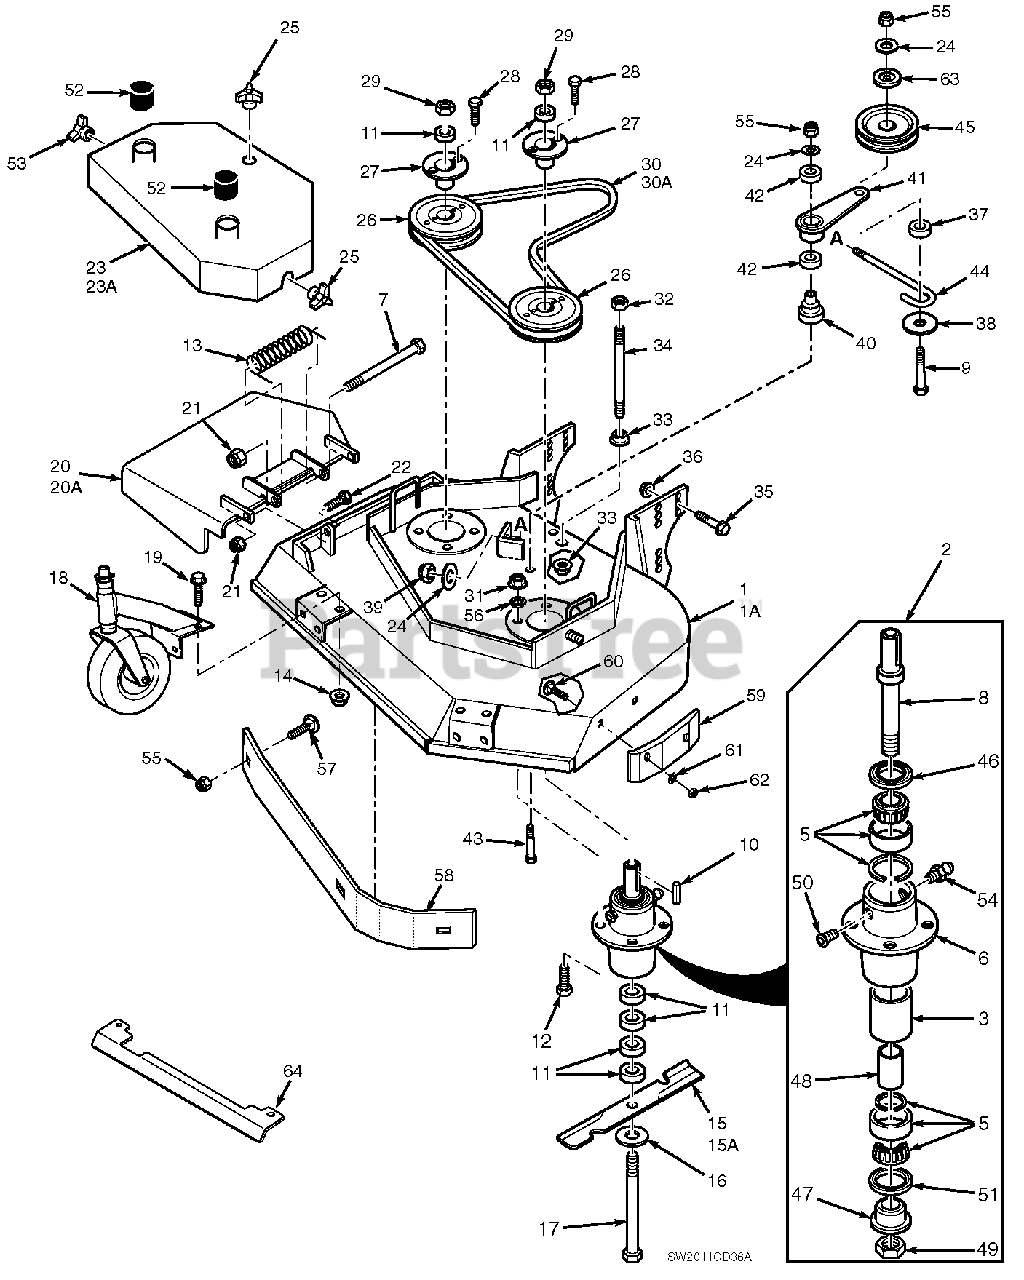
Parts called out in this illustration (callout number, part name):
1	Cutter Deck w/Decals
1A	Cutter Deck w/Decals
1A	Cutter Deck w/Decals - LE
2	Cutter Spindle Assembly
3	Spacer, Outside
5	Bearing, Tapered
6	Spindle Housing
7	Bolt, 5/16-18 x 4-3/4"
8	Spindle Shaft
9	Bolt, 3/8-16 x 3-3/4" Hex Head
10	Key, 1/4 x 1/4 x 2"
11	Spacer, Cutter Blade - Small
12	Bolt, 5/16-18 x 1-1/2" Hex Head Grade 8
13	Spring, Chute Return
14	Nut 5/16-18 Serrated Flange
15	Cutter Blade, 16-1/2"
15	Cutter Blade, 18"
15A	Cutter Blade 16-1/2 Hi-Lift
15A	Cutter Blade, 18 Hi-Lift
16	Flatwasher, 5/8 W
17	Hex Hd. Bolt, 5/8-11 x 9-1/2"
18	Caster Assembly
19	Cpscrw,5/16-18 x 3/4" Ser.Flg. Hex Head
20	Discharge Chute
20A	Discharge Chute
20A	Discharge Chute - LE
21	Hex Nut, 5/16-18 Elastic Stop
22	Hex Hd Bolt, 5/16-18 x 1"
23	Belt Cover Assy
23A	Belt Cover Assy
24	Flat Washer, 3/8" Special
25	Wing Nut, 3/8-16
26	Pulley
27	Tapered Hub
28	Hex Hd. Bolt, 1/4-20 x 1"
29	Hex Nut, 5/8-11
30	Belt, Blade Drive
30A	Belt, Blade Drive
31	Elastic Stop Nut, 5/16-18 Grade 8
32	Hex Nut, 3/8-16 Center Locknut
33	Nut, 3/8-16 Serrated Flange
34	Support, Belt Cover
35	Cpscrw, 1/2-13 x 1"Ser.Flg. HH
36	Nut, 1/2-13 Spiralock
37	Spacer, J-Hook
38	Flatwasher, 3/8 x 1-1/2 x 16 GA
39	Elastic Stop Nut, 3/8-16
40	Idler Pivot
41	Idler Arm Assy.
42	Bearing
43	Cpscrw, 3/8-16 x 3-1/4" Hex Head
44	J-Hook
45	Idler Pulley, Belt Clutch
46	Seal, Cutter Spindle
47	Spindle Bushing
48	Spacer, Inside
49	Nut,1.06-18
50	Relief Fitting, Cutter Spindle
51	Seal, Cutter Spindle
52	Cap, Spindle
53	Wing Nut, 3/8-16 (Small) RH side
54	Grease Fitting
55	Nut, Hex Elastic Stop 3/8-16
56	Lock Washer, 5/16"
57	Bolt, Carriage 3/8-16 x 1"
58	Baffle Weldment
59	Pad, Deck Wear
60	Bolt, Carriage 5/16-18 x 3/4"
61	Flatwasher, 5/16"
62	Hex Nut, 5/16-18 Center Locknut
63	Dust Shield
64	Heatshield
